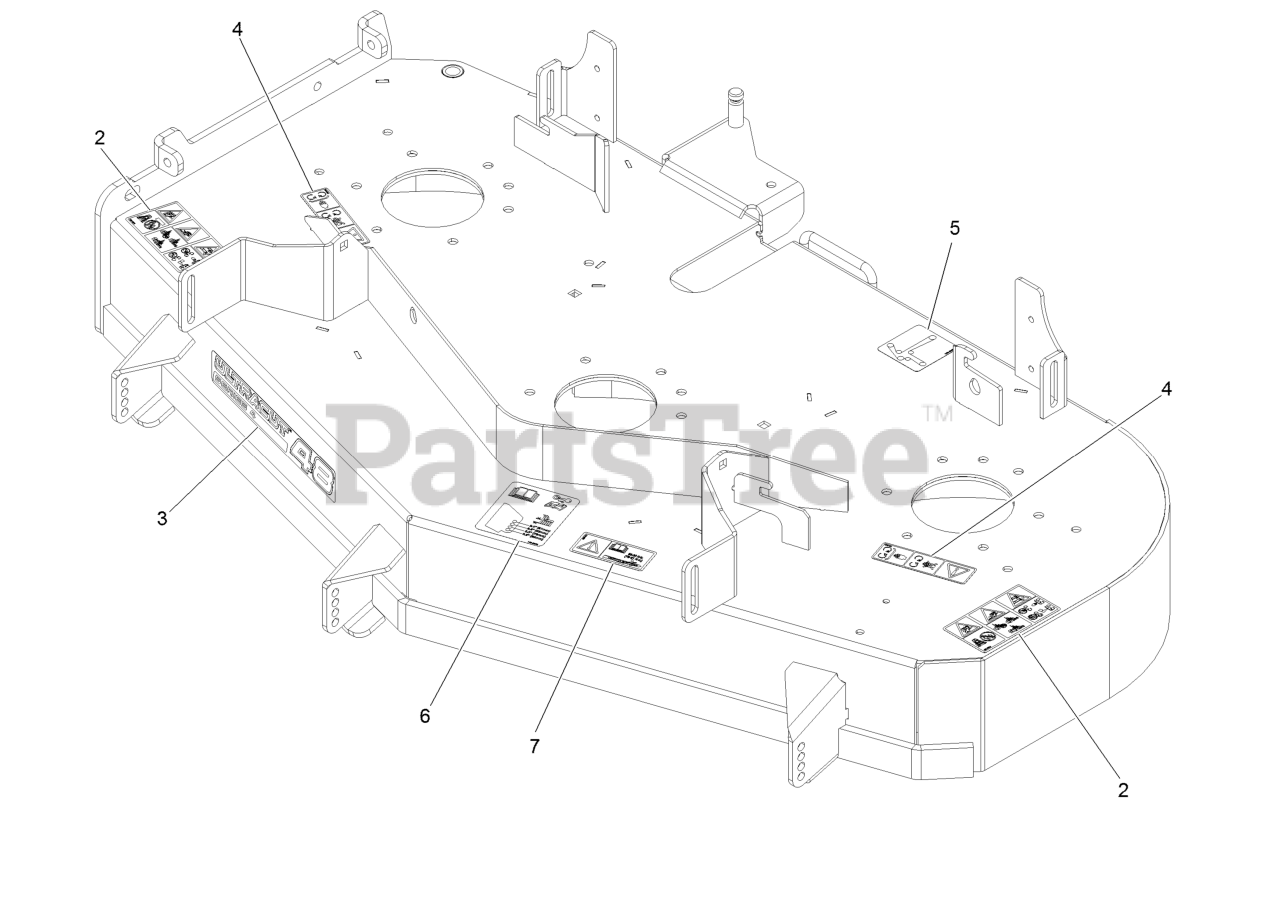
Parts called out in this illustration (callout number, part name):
2	Decal-Danger Thrown Objects
3	Decal, 484
4	Decal-Missing, Cover
5	Decal-Routing, Belt
6	Decal-Roller, Anti-Scalp
7	Decal-Bolt Torque
